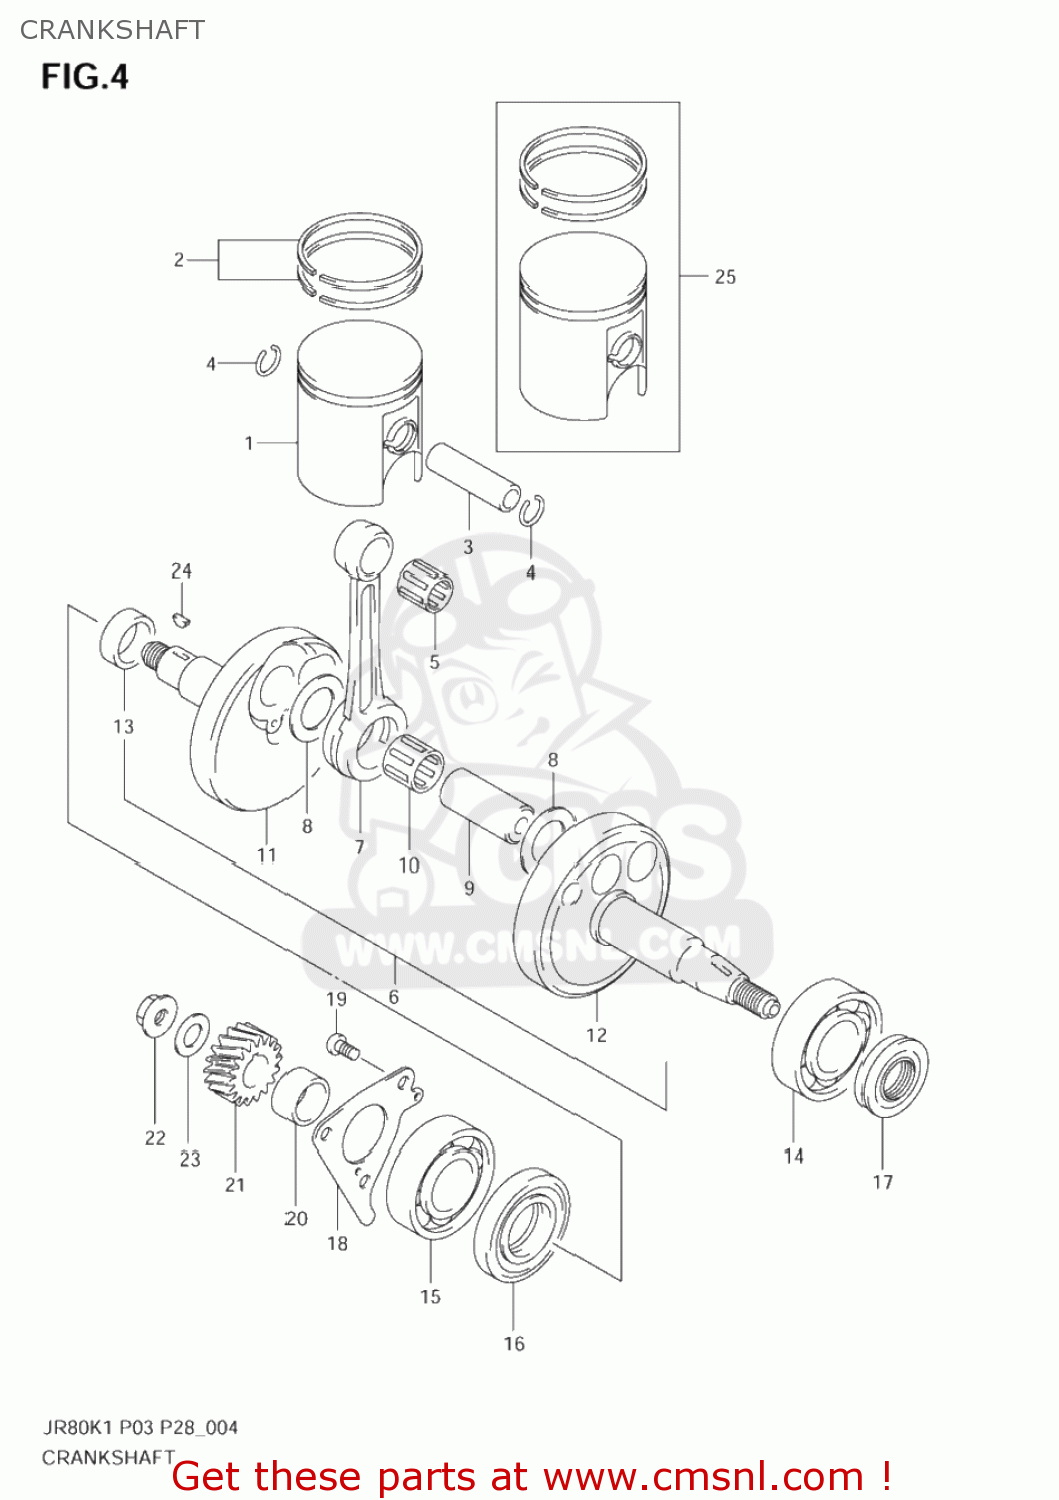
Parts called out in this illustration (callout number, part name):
1	PISTON
2	RING SET,PISTON
3	PIN,PISTON
4	RING,SNAP
5	BEARING(12X16X16)
6	CRANKSHAFT ASSY
7	ROD,CONNECTING
8	WASHER(17X29X1)
9	PIN,CRANK
10	BEARING(17X23X14)
11	CRANKSHAFT,R
12	CRANKSHAFT,L
13	SPACER(20X26X9)
14	BEARING
15	BEARING(20X47X14)
16	SEAL,OIL(26X47X7.3)
17	SEAL,OIL(19.6X37X8)
18	RETAINER,CRANKSHAFT BEARING,R
19	SCREW
20	SPACER(20X26X14)
21	GEAR,PRIMARY DRIVE NO.19
22	NUT
23	WASHER
24	KEY
25	PISTON SET(OS:0.5)
